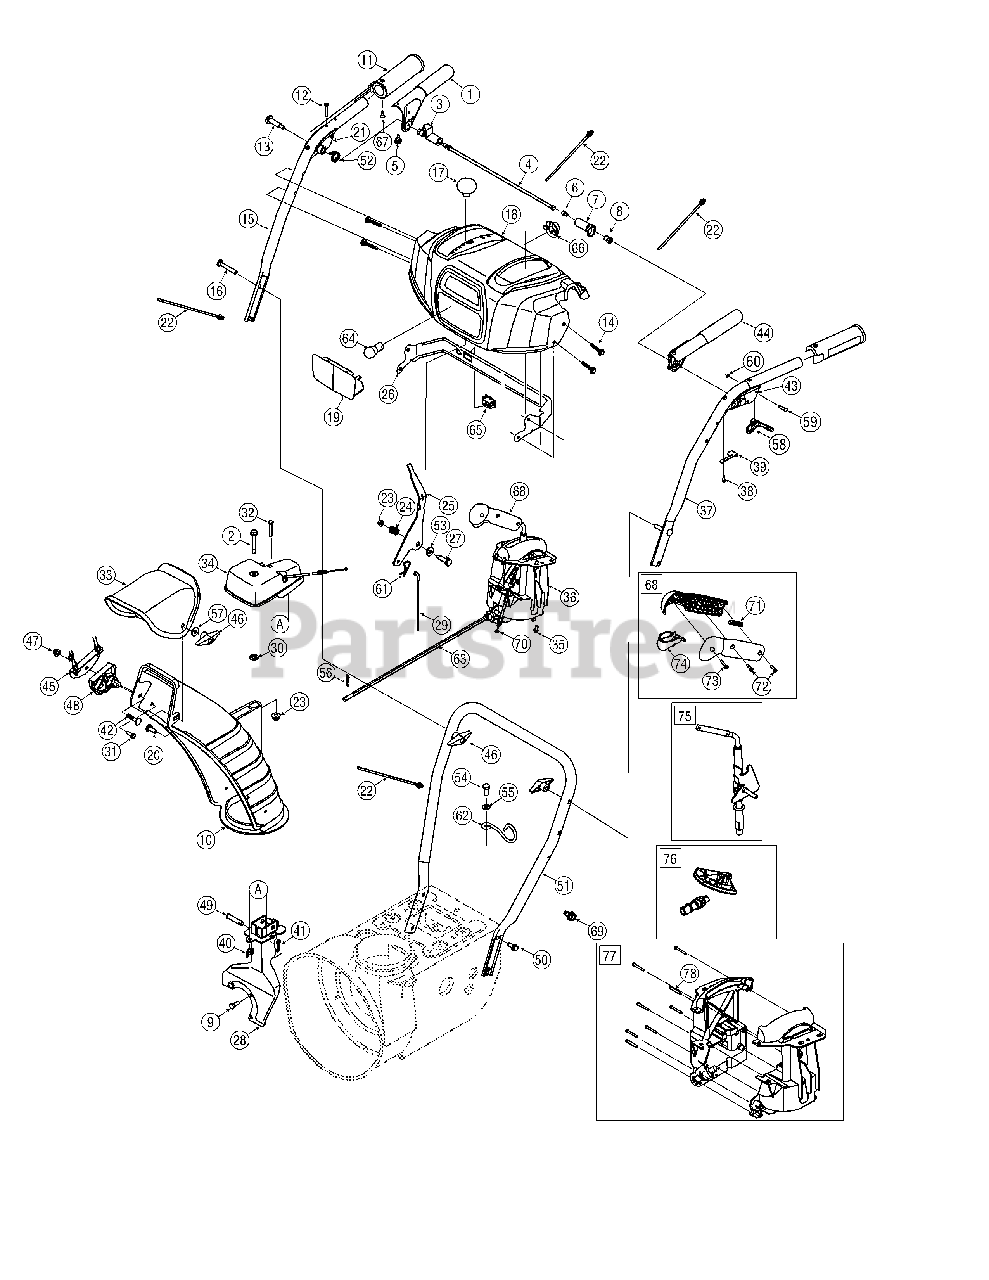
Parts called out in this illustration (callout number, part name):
1	Handle Engagement Assembly RH
2	Flange Shoulder Screw
3	Lock Plate
4	Pivot Rod
5	Rubber Bumper
6	Screw, 1/4-20 x .500
7	Clutch Lock Cam
8	Shoulder Nut, 1/4-20
9	Hex Screw, 5/16-24 x .750
10	Lower Chute
11	Heated Grip
12	Screw, #10-24 x 0.375
13	Shoulder Screw, 1/4-20
14	Screw, 1/4-20 x 1.625
15	Upper Handle RH
16	Carriage Screw, 5/16-18 x 2.25
17	Shift Knob
18	Handle Panel
20	Carriage Bolt, 5/16-18 x 1.0
21	Handle Clutch Lock Assembly - RH
22	Cable Tie
23	Flange Lock Nut, 1/4-20
24	Compression Spring
25	Shift Lever
26	Panel Bracket
27	Shoulder Screw
28	Chute Support Bracket
29	Speed Selector Cable
30	Flat Washer, .25 x .630 x .0515
31	Hi-Lo Screw, 1/4-15 x .75
32	Hex Screw, 1/4-20 x 3.00
33	Upper Chute
34	4-Way Chute Gearbox Assembly
35	Hi-Lo Screw, 1/4-15 x 0.5
36	4-Way Chute Control™ Assembly
37	Upper Handle LH
38	Screw, #8-16 x 0.50
39	Clutch Lock Spring
40	Wing Nut, 1/4-20
41	Bow Tie Cotter Pin
42	Carriage Bolt, 5/16-18 x 1.50
43	Handle Clutch Lock Assembly - LH
44	Handle Engagement Assembly LH
45	Cable Bracket
46	Wing Knob
47	Flange Lock Nut, 5/16-18
48	Chute Tilt Cable Guide
49	Clevis Pin
50	Screw, 5/16-18 x 0.75
51	Lower Handle
52	Torsion Spring
53	Flat Washer
54	Screw, M8-1.25
55	Flat Washer, .330 x .630 x .0635
56	Cotter Pin
57	Flat Washer, .349 x .879 x .063
58	Steering Control
59	Pin, 3/16
60	E-Ring
61	Click Pin
62	Cable Guide
63	Chute Rod
64	Lamp
65	Switch, Heated Grip
66	Light Socket
67	Screw, #10-16 x .625
68	Handle Assembly
69	Screw (For ground wire)
70	4-Way Cable
70	4-Way Cable w/Clip
71	Handle Plunger
72	Screw, Mach., #8-32 x .750
73	Screw, #8 x 1.00
74	Handle Lever
75	Shift Assembly
76	Gear Set Assembly
77	Handle Housing Assembly
78	Screw, #8-18 x 1.250
